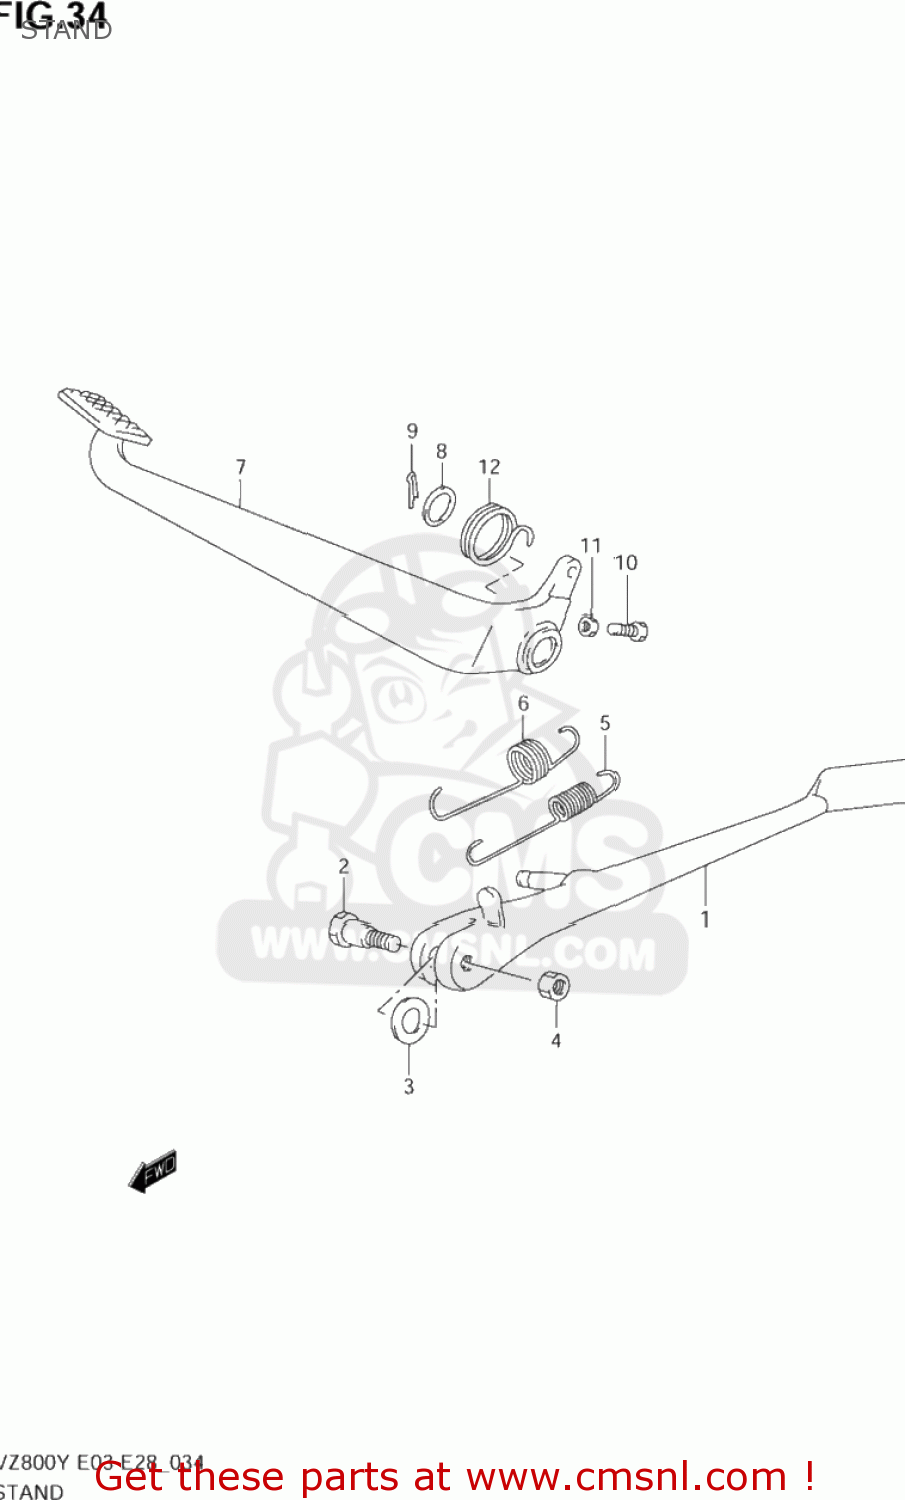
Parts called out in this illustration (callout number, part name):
1	STAND,PROP
2	BOLT(10X34)
3	SHIM
4	NUT
5	SPRING
6	SPRING
7	PEDAL,BRAKE
8	WASHER(16.5X22X1)
9	COTTER PIN
10	BOLT
11	NUT
12	SPRING
